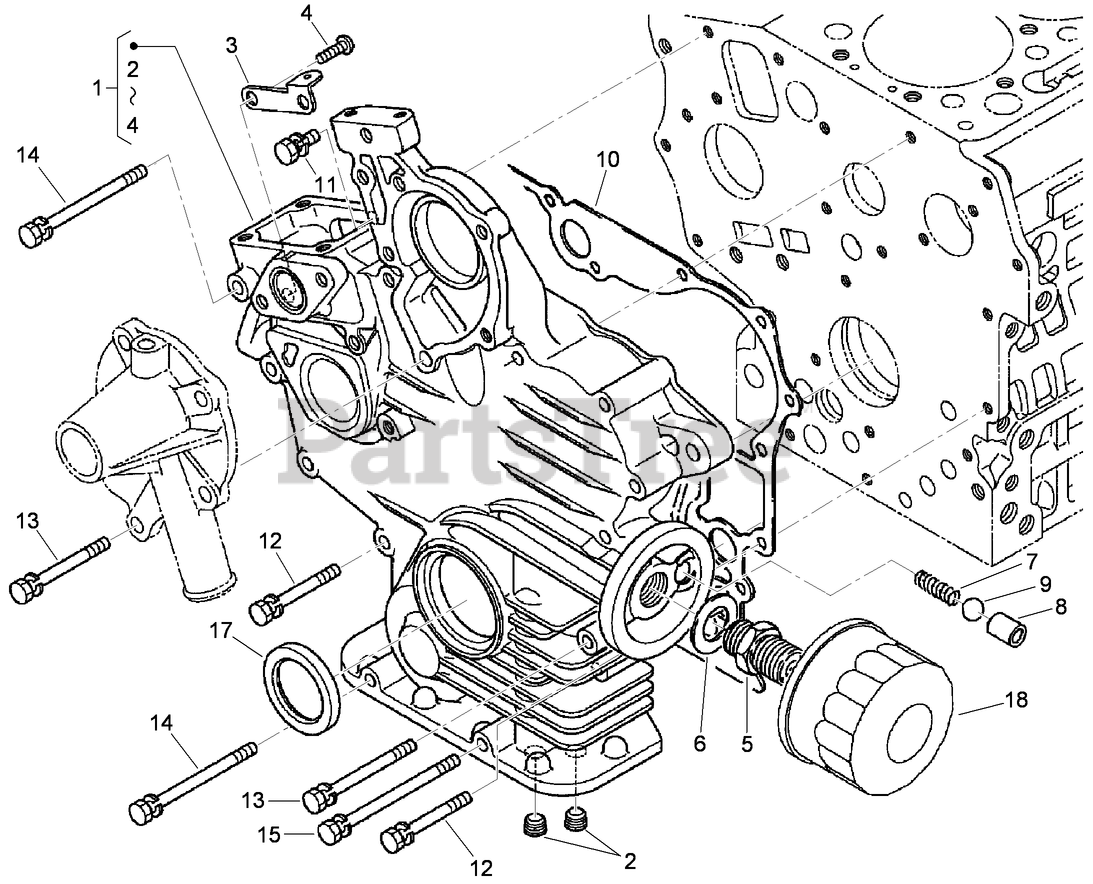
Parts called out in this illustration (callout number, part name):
3	STAY-SPRING, START
5	JOINT-PIPE
6	WASHER-PLAIN
7	SPRING
8	SEAT-VALVE
10	GASKET-CASE, GEAR
